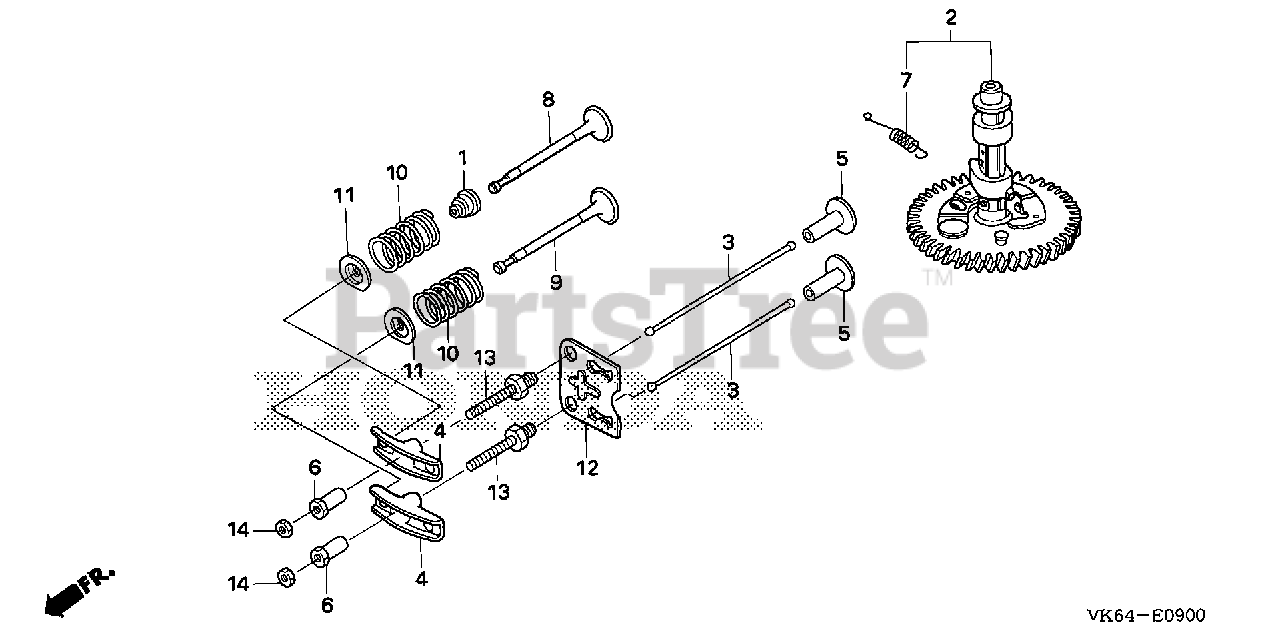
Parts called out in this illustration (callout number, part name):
1	SEAL, VALVE STEM
2	CAMSHAFT ASSY.
3	ROD, PUSH
4	ARM, VALVE ROCKER
5	LIFTER, VALVE
6	PIVOT, ROCKER ARM
7	SPRING, WEIGHT RETURN
8	VALVE, IN.
9	VALVE, EX.
10	SPRING, VALVE
11	RETAINER, IN. VALVE SPRING
11	RETAINER, VALVE SPRING (EXHAUST SIDE)
12	PLATE, PUSH ROD GUIDE
13	BOLT, PIVOT (8MM)
14	NUT, PIVOT ADJ.
